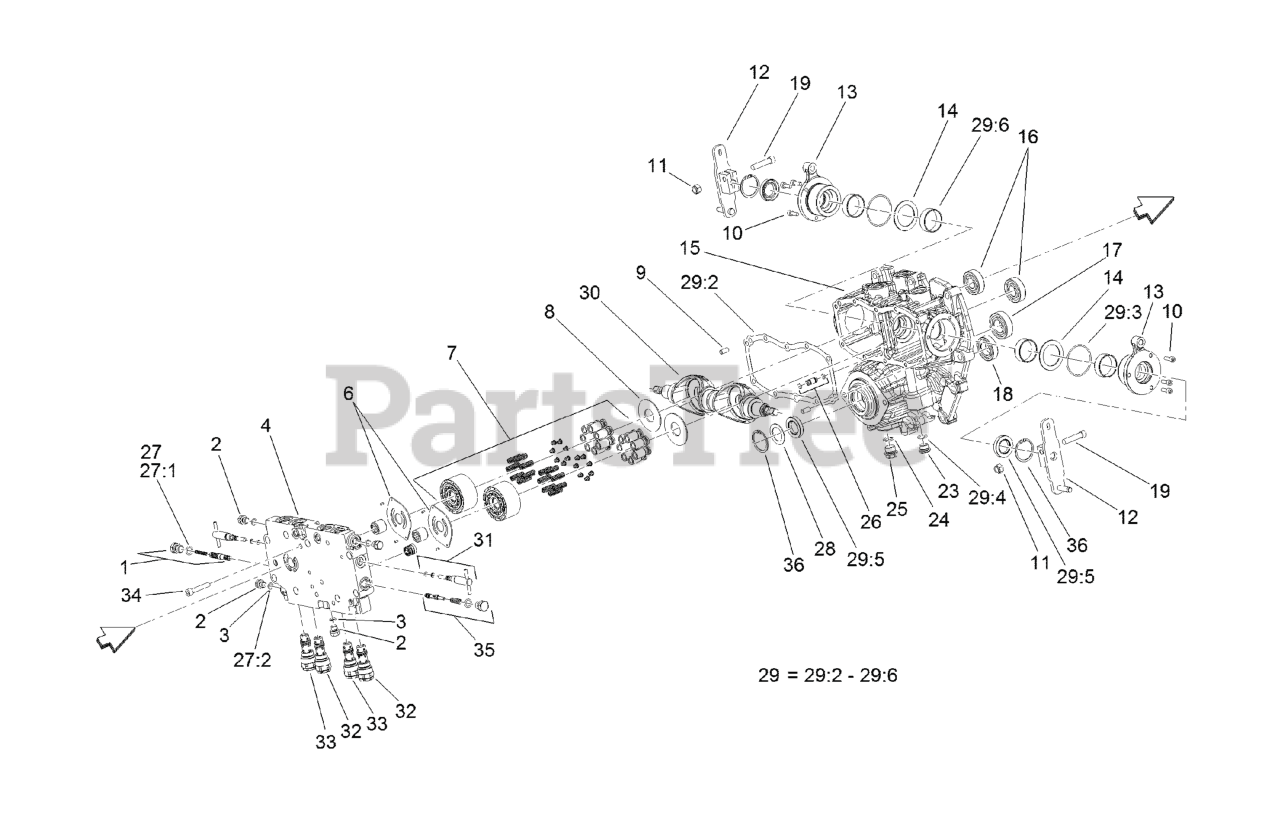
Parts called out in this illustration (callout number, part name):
1	VALVE-FLUSHING, RH
3	O RING-PLUG
4	CENTER CASE, COMPLETE
6	PLATE-VALVE
7	CYLINDER BLOCK ASM
8	PLATE-THRUST
9	PIN-PARALLEL
12	ARM-CONTROL
13	SIDE COVER ASM
15	PUMP HOUSING ASM
16	BEARING
17	BEARING
18	BEARING
23	PLUG-NPTF
24	O-RING
27	CENTER CASE SEAL KIT
27:2	O RING-PLUG
29	PUMP HOUSING SEAL KIT
29:2	GASKET-CASE, CENTER
29:3	O RING-PLUG
29:4	Packing
29:6	RING-SEAL
30	PLATE-SWASH
31	VALVE-BYPASS
32	VALVE-REAR
33	VALVE-FRONT
35	VALVE-FLUSHING, LH
36	RING-SNAP
